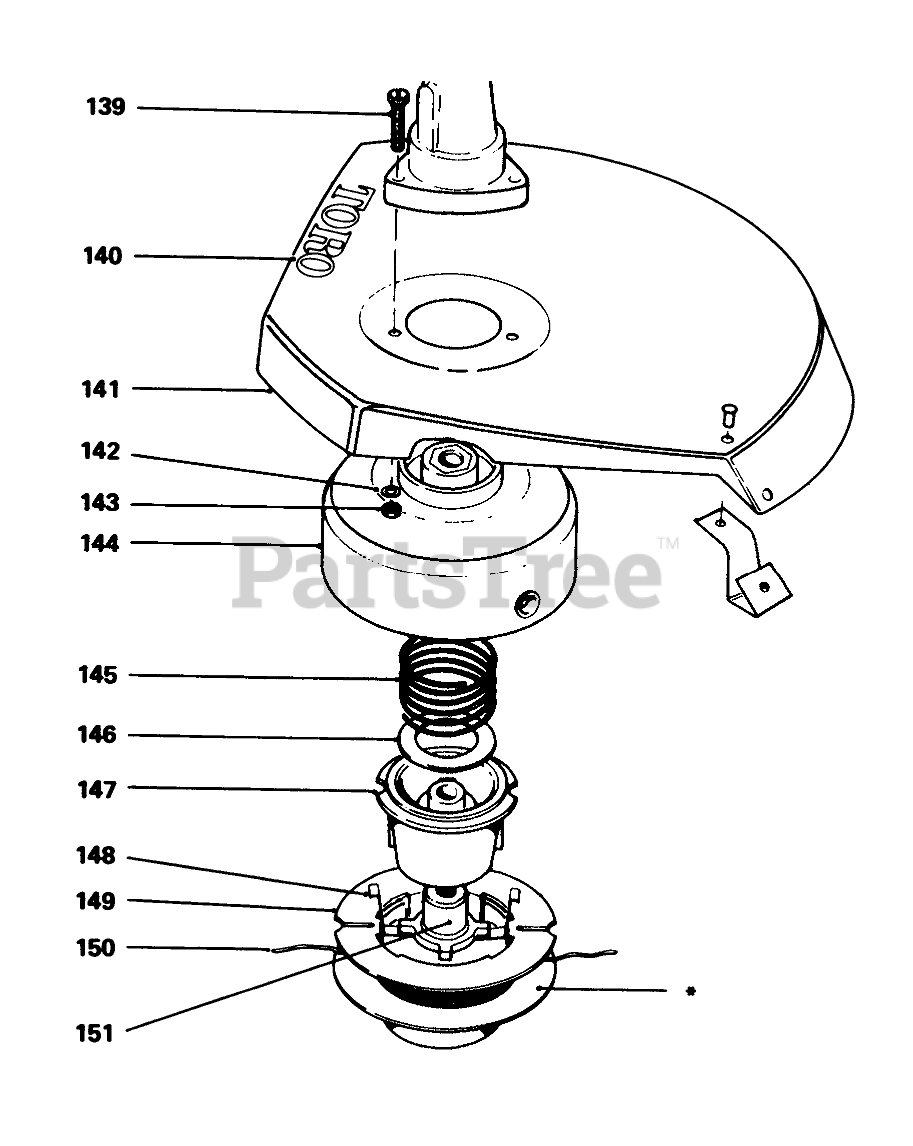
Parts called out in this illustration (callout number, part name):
139	SCREW-SHH
140	Decal, Toro
141	Shield w/cut-off Blade
142	WASHER-LOCK
143	NUT-HEX
144	Drum w/eyelet
145	SPRING
146	WASHER-FLAT
147	SPOOL CORE
148	SADDLE-SPOOL CAP
149	Empty SPooI
150	50-Coil.065" Cutting Line
151	LH DRIVER
